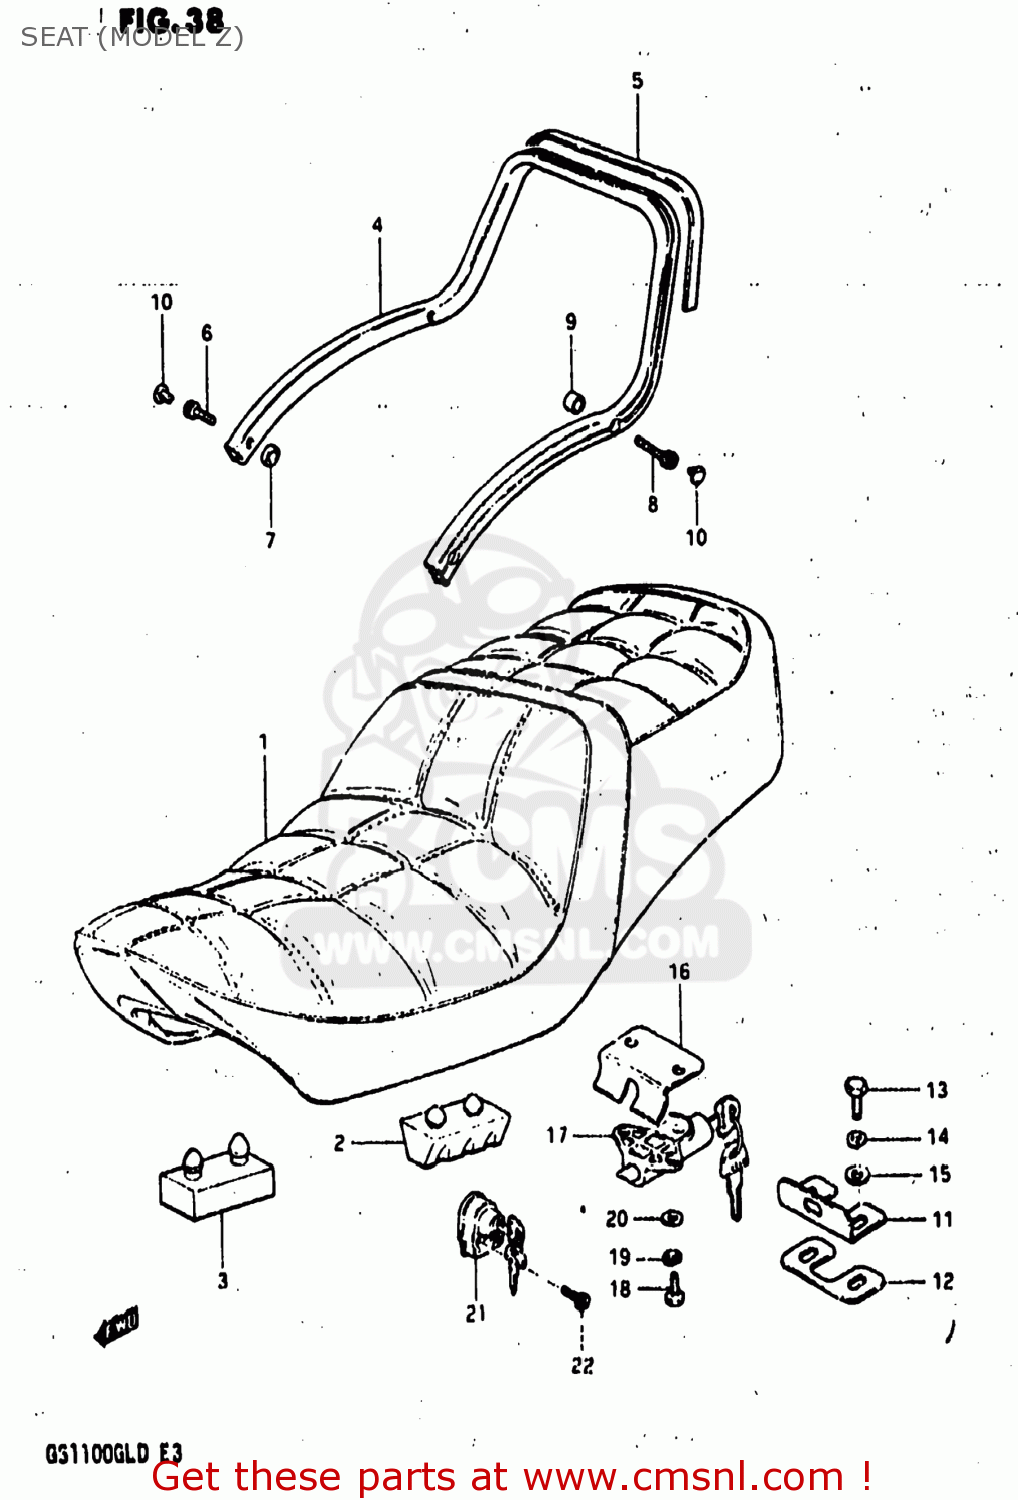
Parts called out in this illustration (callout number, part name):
1	SEAT ASSEMBLY
2	CUSHION,SUPPORT(50X25X32)
3	CUSHION
4	HANDLE,PILLION RIDER
5	RUBBER,PILLION RIDER HANDLE
6	BOLT
7	SPACER,REAR
8	BOLT
9	SPACER,REAR
10	CAP(OD:14.5)
11	STRIKER,SEAT LOCK
12	SHIM,SEAT LOCK STRIKER
13	BOLT, UPPER
14	LOCK WASHER
15	WASHER
16	PLATE,SEAT LOCK
17	LOCK ASSEMBLY,SEAT
18	BOLT
19	LOCK WASHER
20	WASHER 6MM
21	LOCK ASSY,HELMET
22	BOLT 5X25
